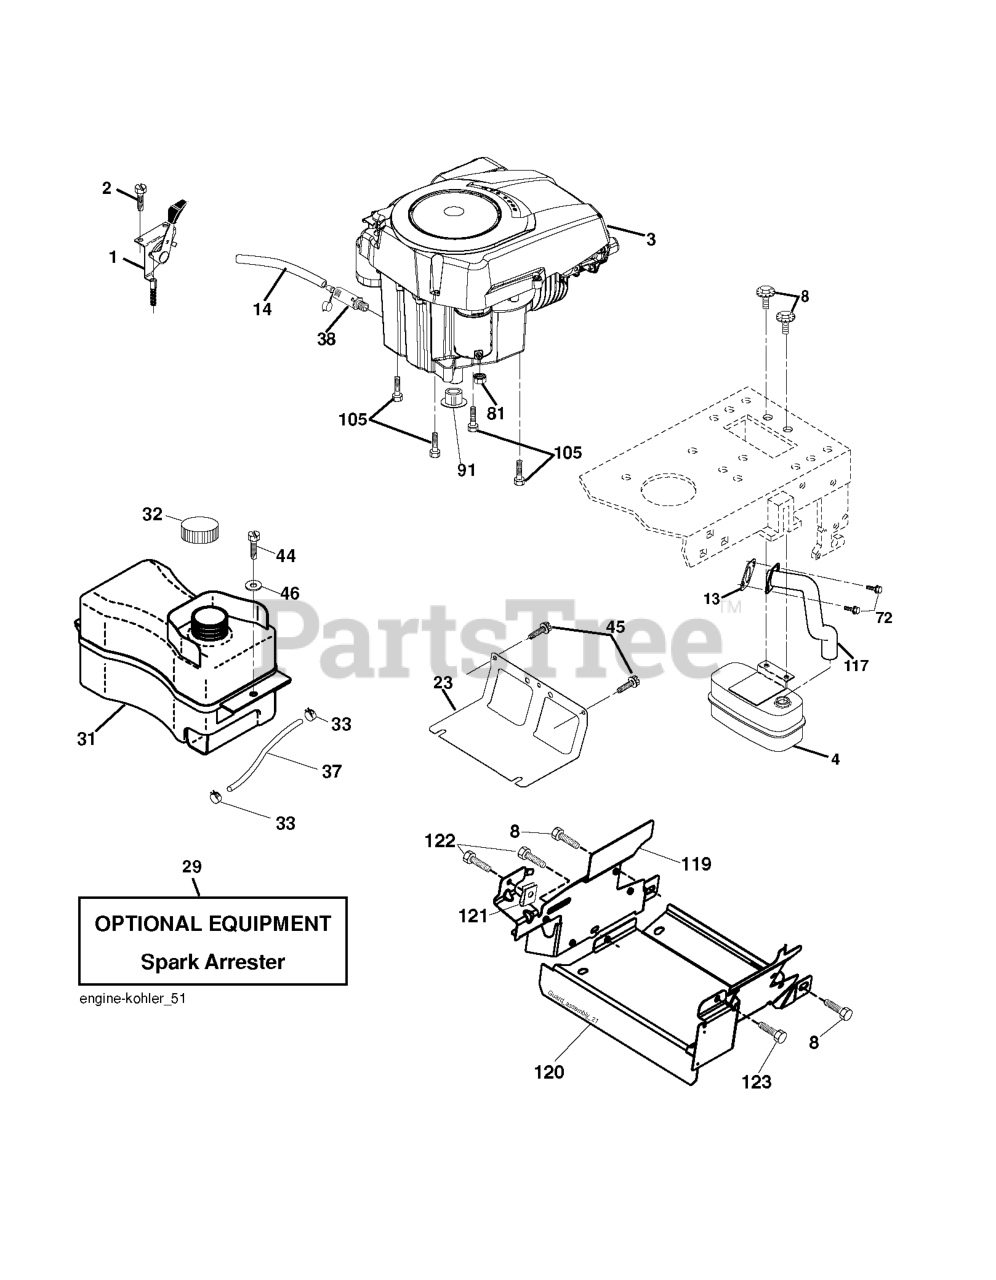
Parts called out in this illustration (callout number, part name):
1	CONTROL.TH/CK.C.
2	SCREW
4	MUFFLER.SINGLE.CYL.KOHL/B&S
8	BOLT.5/16-18UNCX3/4 W/SEMS.BLK
13	GASKET.EXHAUST.KOHLER
14	TUBE, DRAIN OIL ASM.
23	SHIELD.BROWNING.DBR.GUARD
29	KIT.SPARK ARRESTOR 794945 B&S
31	RP TANK FUEL FRT 1.5 GAL
32	FUEL CAP
33	HOSE CLAMP
37	LINE.FUEL.20
38	PLUG DRAIN OIL EASY
44	SCREW HEXWSHR 1/4-20X3/4
45	SCREW, 3/8-16X3/4
72	SCREW.SOCKET HD.5/16-1
81	NUT
91	BUSHING.1.375OD
105	SCREW 3/8-16X1
117	RP.TUBE.EXHAUST.KOHL.COURAGE
119	LENKRAD
120	GUARD 532199767
122	SCREW.1/4-20X5/8
123	SCREW, 5/16-18 X 1/2
